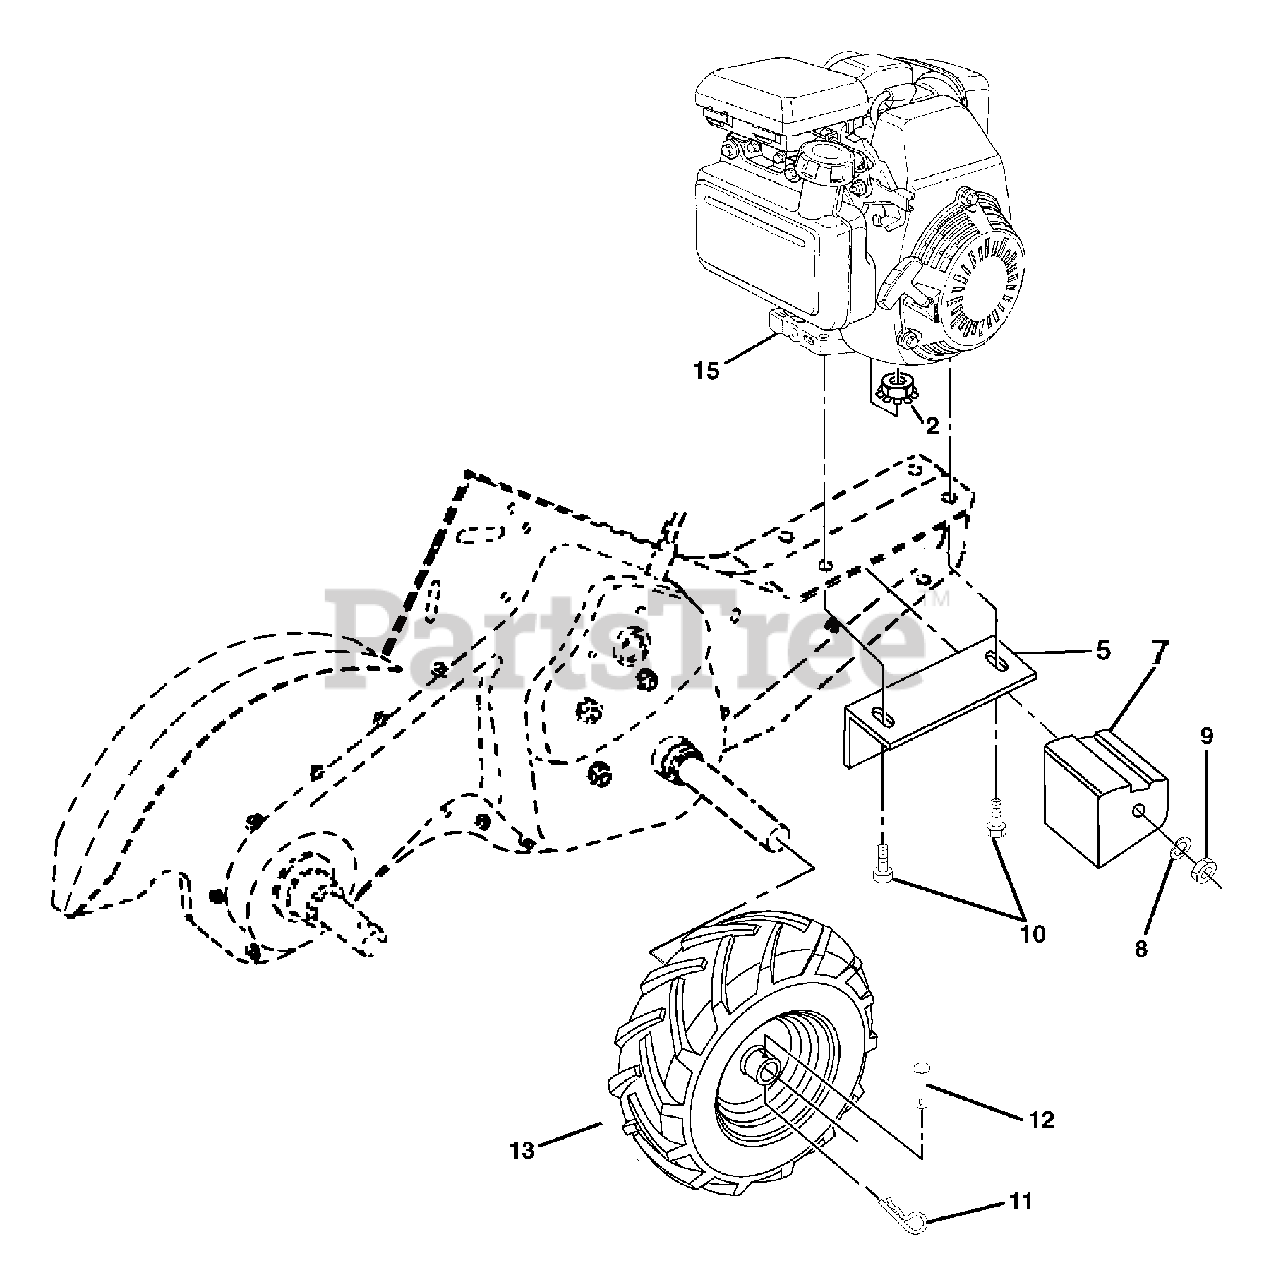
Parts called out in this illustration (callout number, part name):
2	Locknut, Hex, Flange 5/16-18
5	Bracket, Reinforcement
7	Counter Weight, R.H.
8	Washer, Lock 3/8
9	Nut, Hex 3/8-16
10	Bolt, Hex 5/16-18 x 1-1/2
11	Clip, Hairpin
12	Rivet, Drilled
13	Tire Valve
15	Engine, Honda
